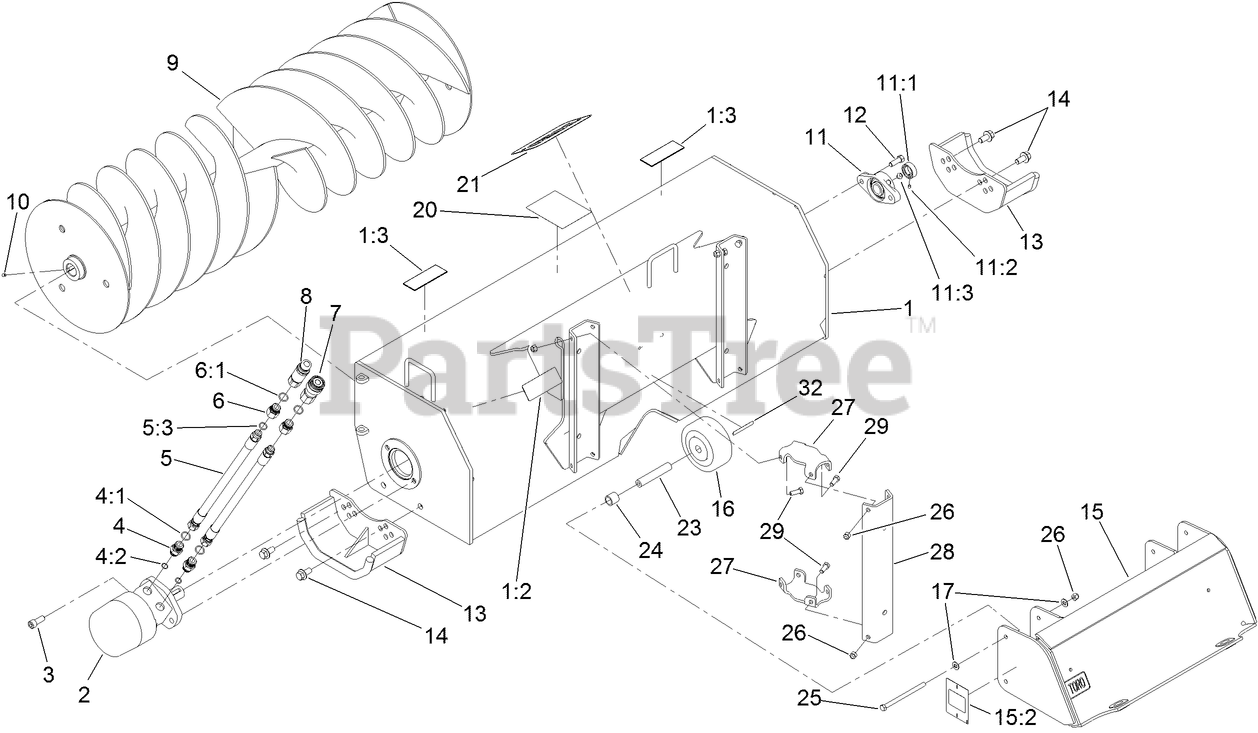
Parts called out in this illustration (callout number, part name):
1	FRAME ASM
1:2	DECAL-WARNING
1:3	DECAL-DANGER
2	HYDRAULIC MOTOR ASM
3	SCREW-HSH
4	FITTING-STRAIGHT
4:1	O-RING
4:2	O-RING
5	HOSE ASM
5:3	O-RING
6	ADAPTER-HYD
6:1	O-RING
7	COUPLER-FACE, FLUSH
8	NIPPLE-CONNECT, PRESSURE
9	FILLER SHAFT ASM,
10	SCREW-HSH
11	BEARING
11:1	COLLAR W/SET SCREWS
11:2	SCREW-SET, HSH
11:3	FITTING-GREASE
12	SCREW-HH
13	SKID PLATE ASM
14	SCREW-HHF
15	QTACH ASM
15:2	DECAL-WARNING
16	ROLLER-FLOAT
17	WASHER-FLAT
20	DECAL-CENTER TRENCH
21	DECAL
23	SPACER-FLOAT
24	SPACER-WHEEL
25	SCREW-HH
26	NUT-LOCK, NI
27	BRACKET-CAP, FLOAT
28	BRACKET-GUIDE, FLOAT
29	SCREW-HH
32	DECAL-WARNING
